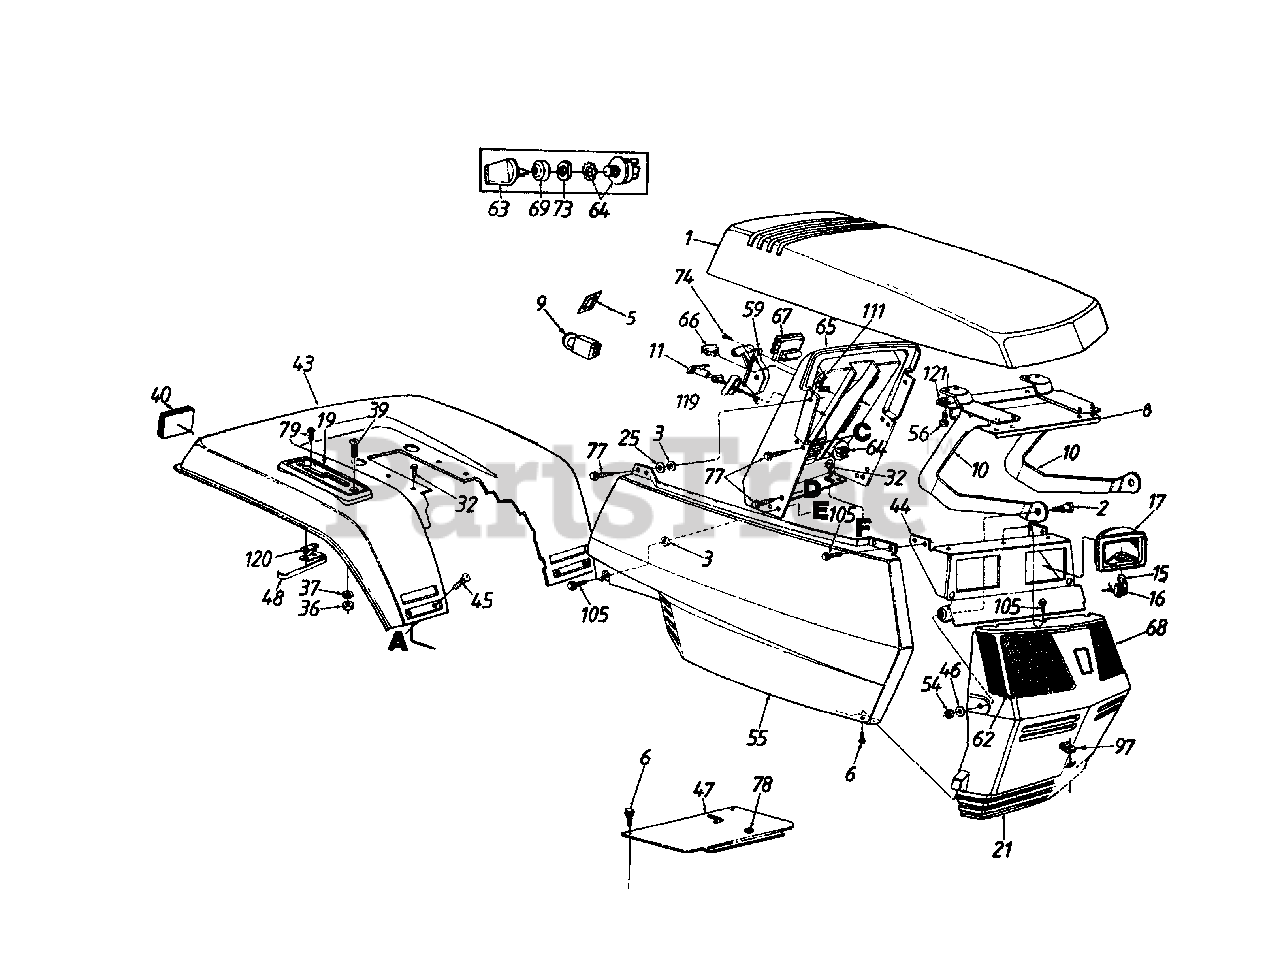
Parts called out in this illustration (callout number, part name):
1	Hood Ass'y.
2	Shld. Bolt .437" Dia. x .35"
3	Bolt Retainer 1/4" I.D.
5	Switch Retainer
6	Truss Mach. B-Tap Scr.#10 x .5" Lg.
15	Lamp
16	Twist Lock-Lamp Socket
17	Headlight Housing
19	Speed Control Index Brkt.
21	Grille
25	Fl-Wash. 1/4" I.D. x .93" O.D.
32	Hex Wash. Hd. AB-Tap Scr.5/16 x .75" Lg.
39	Truss Mach. Scr. 1/4-20 x 1.0" Lg.
40	Reflector
46	Fl-Wash. .328" I.D. x .68" O.D.
54	Hex Cent. L-Nut 5/16-18 Thd.
55	Side Panel Ass'y.
56	Hex Wash. Hd. B-Tap Scr. 1/4 x .5" Lg.
62	Lens-R.H.
63	Ignition Key
64	Ignition Switch
65	Dash Panel
67	Ammeter
68	Lens-L.H.
69	Ignition Switch Cap
73	Ignition Switch Nut
74	Truss Mach. AB-Tap Scr.#10 x .5" Lg.
77	Hex Wash. Hd. Tap Scr. 1/4 x .75" Lg.
78	Snap Bushing
105	Hex Tap Scr. 1/4-20 x .5" Lg.
111	Speed Nut 1/4-20 Thd.
119	Retainer Clip
120	Insulator Nut Plate
